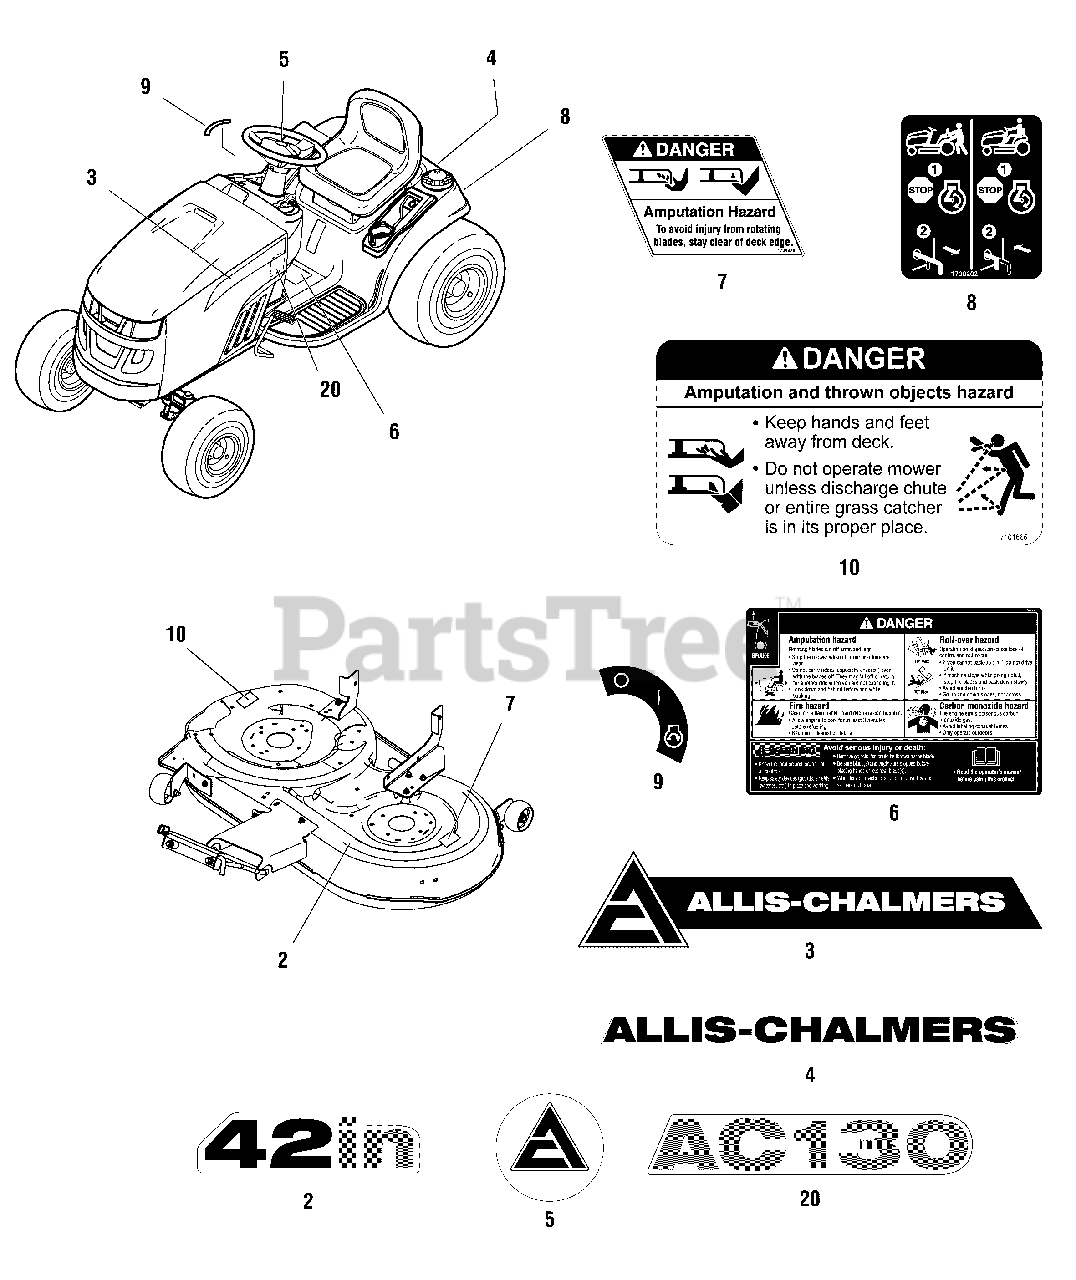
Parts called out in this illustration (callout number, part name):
2	DECAL, Cut, 42
3	DECAL, Stripe, Allis Chalmers, With Logo
4	DECAL, Allis Chalmers, Rear
5	DECAL, Steering Wheel
6	DECAL, Tunnel
7	DECAL, Danger, Hands / Feet
8	DECAL, Transmission Tow, Release Lever
9	DECAL, Ignition Switch
10	DECAL, Danger Do Not Operate Without Deflector
20	DECAL, Model AC130
